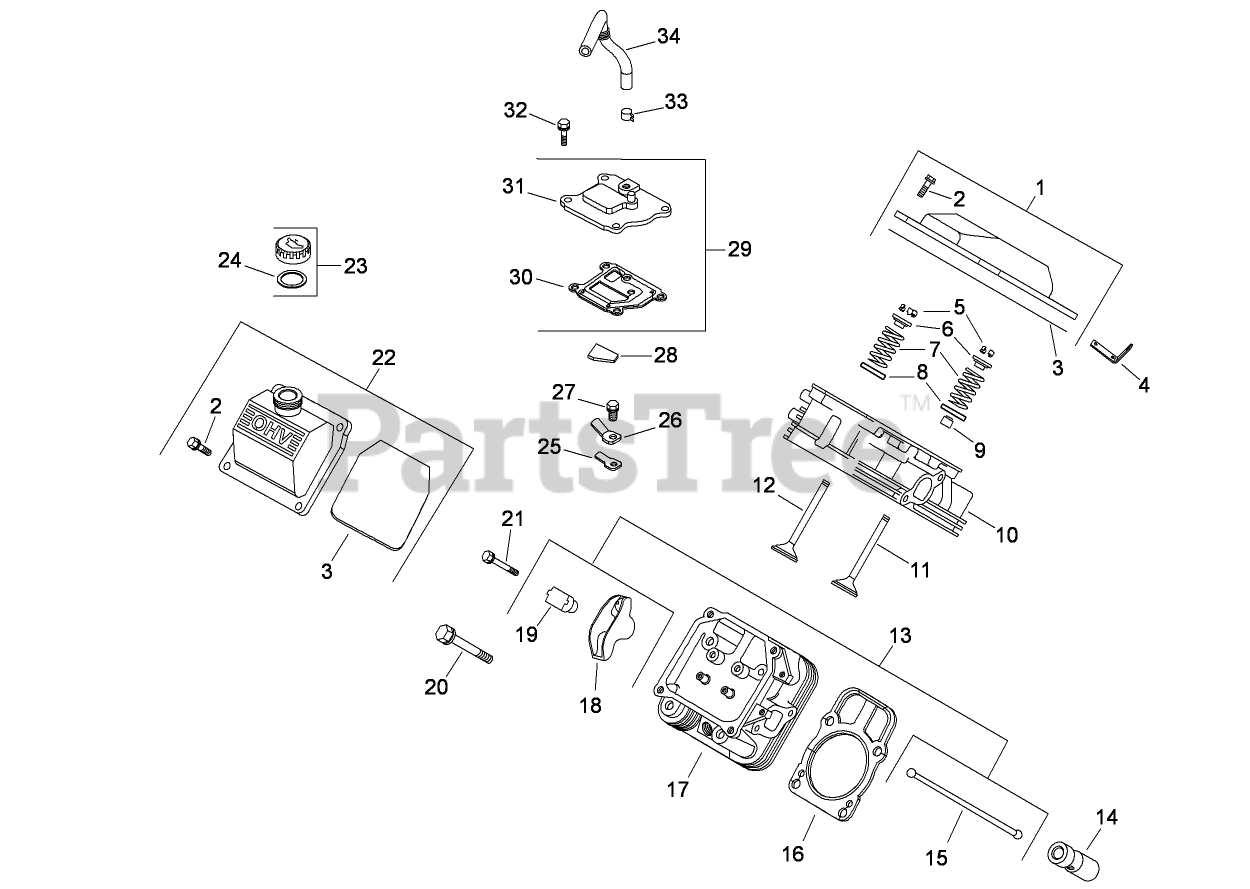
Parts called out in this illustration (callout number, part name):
1	Plain Valve Cover ASM (Includes 2, 3)
2	SCREW-FLANGE (M6X1.0X30)
3	O-Ring (Valve Cover)
4	STRAP-LIFTING
5	RETAINER KIT
6	CAP-SPRING, VALVE
7	SPRING-VALVE
8	RETAINER-SPRING
9	SEAL-STEM, VALVE
10	No. 1 Cylinder Head ASM
11	VALVE-INTAKE (STD)
11	VALVE-INTAKE (.25)
12	VALVE-EXHAUST (STD)
12	VALVE-EXHAUST (.25)
13	Valve Train Kit (Includes 15, 18, 19)
14	Lifter-Valve (Includes Camshaft Lubricant)
15	ROD-PUSH
16	Cylinder Head Gasket Kit (Includes Gaskets, Nut and O-Ring)
17	No. 2 Cylinder Head ASM (Includes Stud)
18	ARM-ROCKER
19	PIVOT-ARM, ROCKER
20	SCREW-FLANGE (M10X1.5X90)
21	SCREW-FLANGE (M6X1.0X34)
22	Valve Cover Oil Fill ASM (Includes 2, 3)
23	Oil Fill Cap ASM (Yellow) (Includes 24)
24	O-Ring (Dipstick)
25	REED-BREATHER
26	RETAINER-REED
27	SCREW-HHFTF (M5X.80X10)
28	FILTER-BREATHER
29	Breather Kit (Includes 30, 31)
30	GASKET-BREATHER
31	COVER-BREATHER
32	SCREW-HHFTF (M6X1.0X20)
33	CLAMP-HOSE, SPRING (1/2)
34	HOSE-BREATHER
